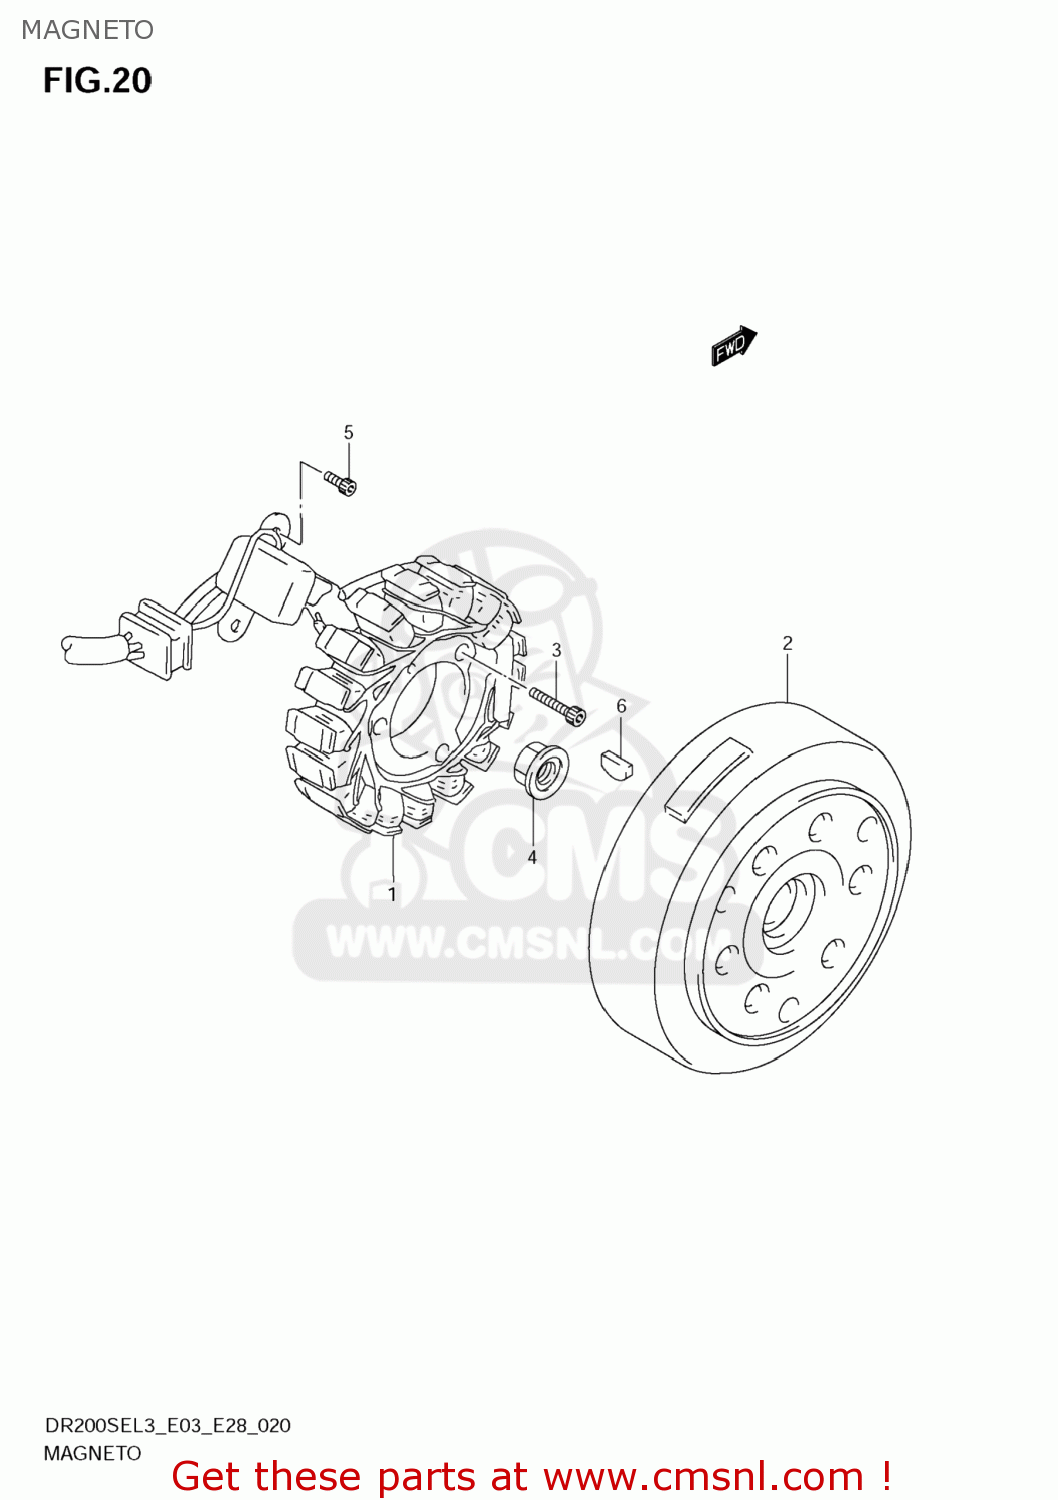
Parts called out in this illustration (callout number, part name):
1	STARTER ASSY
2	ROTOR ASSY
3	BOLT
4	NUT,MAGNETO ROTOR
5	BOLT
6	KEY
